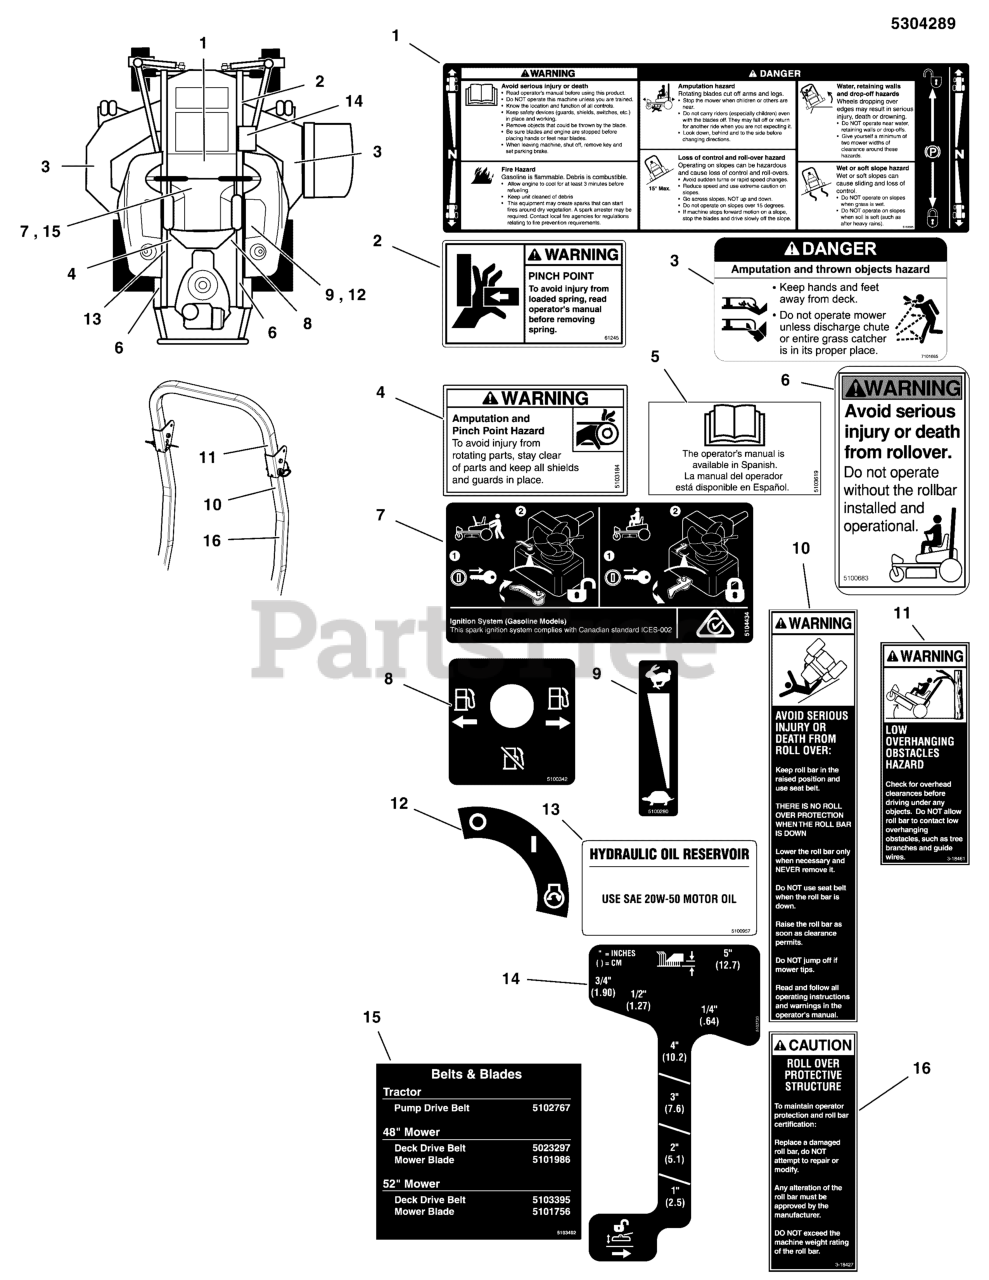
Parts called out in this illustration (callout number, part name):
1	DECAL, MAIN SAFETY
2	DECAL, PINCH POINT
3	DECAL, DANGER DO NOT OPERATE W/O DEFLECT
4	DECAL, WARNING, HAND IN BELT, ENG ONLY
5	DECAL, MANUAL AVAIL IN SPANISH
6	DECAL, WARNING, ROLL BAR
7	DECAL, TRANSAXLE RELEASE, ZT4400
8	DECAL, FUEL VALVE
9	DECAL, THROTTLE CONTROL
10	DECAL, WARNING, FLDG ROPS
11	DECAL, WARNING OVERHANG, ROPS
12	DECAL, IGNITION SWITCH
13	DECAL, HYDRAULIC OIL, SAE 20W50
14	DECAL, CUT HEIGHT, S150XT
15	DECAL, BELT & BLADE, S150XT
16	DECAL, CAUTION, FLDG ROPS
